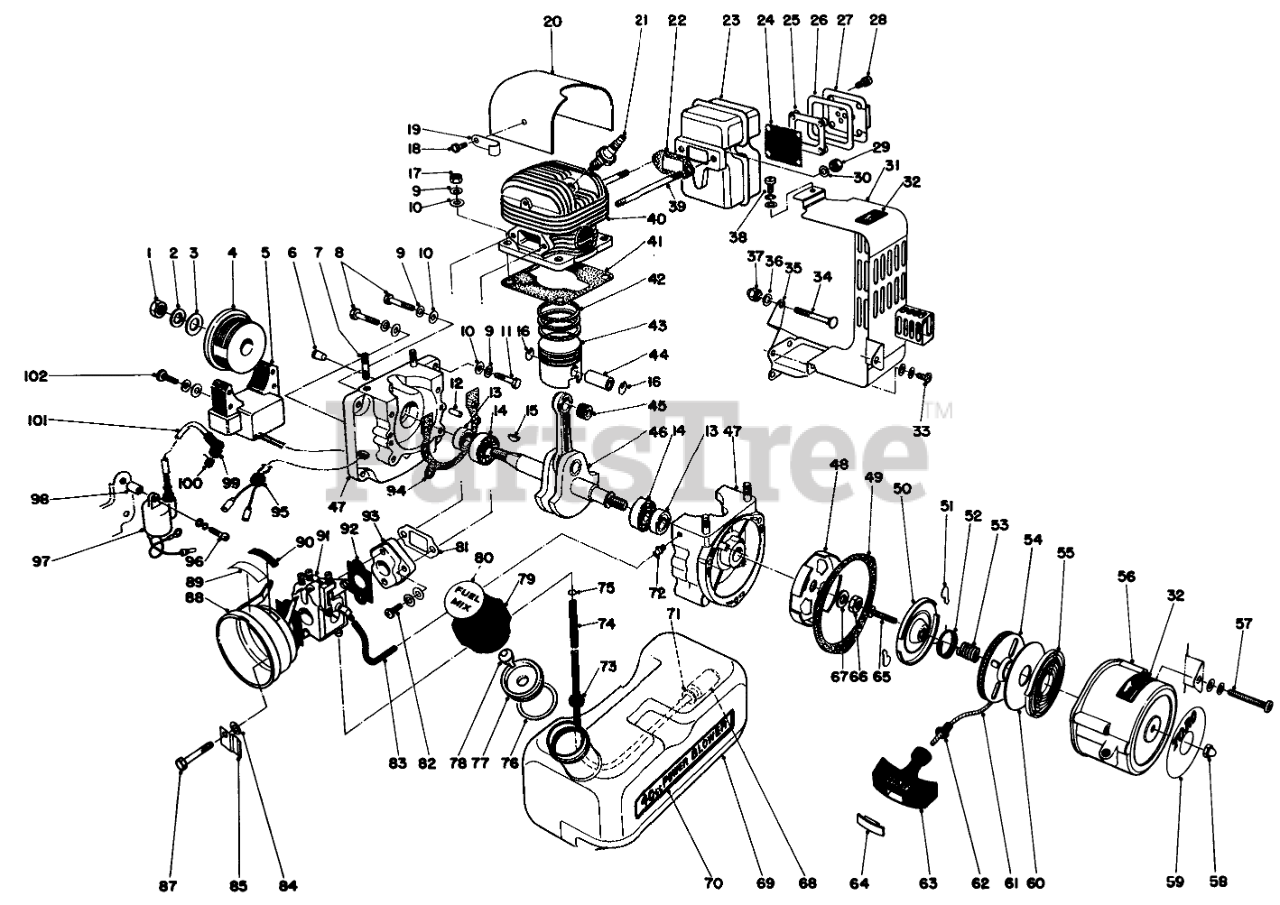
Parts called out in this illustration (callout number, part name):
2	Spring Washer
3	Washer
4	Rotor
5	C.D.I. MODULE - ECHO
7	Stud Bolt
9	Washer
10	Washer
12	Knockpin
13	Oil Seal
14	Ball Bearing
15	Woodruff Key
16	CIRCLIP PISTON PIN
19	Clamp
20	Cylinder Cover
21	Spark Plug
22	Gasket Muffler
23	Muffler Assembly (Incl. Ref.#22-30, 35 & 39)
24	Screen
25	Seat Screen
26	Packing Holder
27	Holder Screen
28	Screw
29	LOCKNUT
30	Washer
31	MUFFLER COVER
32	Decal-Hot Surface
33	Screw
34	Bolt, Elbow
35	Bracket-Muffler Cover
36	WASHER
37	Capnut
38	Screw
40	Cylinder
41	Packing Cylinder Base
42	PISTON RING
43	Piston
44	Piston Pin
45	Needle Bearing
46	Crankshaft Assembly
47	Crankcase Set
48	PAWL CATCHER
49	STARTER CASE GASKET
50	FRICTION PLT
51	RATCHET
52	RATCHET SPRING
53	SPRING
54	Recoil Drum
55	REWIND SPRING
56	Starter Case
57	SCREW
58	Cap Nut
59	Decal-Toro
60	Side Plate, Starter
61	Starter Rope
62	Rope Guide
63	Starter Handle
64	Cap, Starter Handle
65	Screw
67	Washer
68	Fuel Strainer
69	Fuel Tank
70	Decal-40cc
71	Washer
72	Connector
73	GROMMET
74	FUEL PIPE
75	Clip Fuel Pipe
76	Handle-Door
77	Holder, Check Valve
78	Check Valve
79	FUEL TANK CAP - WILLMAR
80	Decal-Fuel Mix
81	GASKET
82	SCREW
84	Washer
85	Choke Clip/Washer (Incl. Ref. #84)
88	CLEANER CASE-WILLMAR
89	Decal-Caution
91	CARBURATOR ASM
92	GASKET
93	INSULATOR
94	Packing, Crankcase
95	Grommet
96	Screw
97	IGNITION COIL
98	Spacer
99	Cap-Spark Plug
100	Coil Spring-Plug Cap
101	Sleeve
